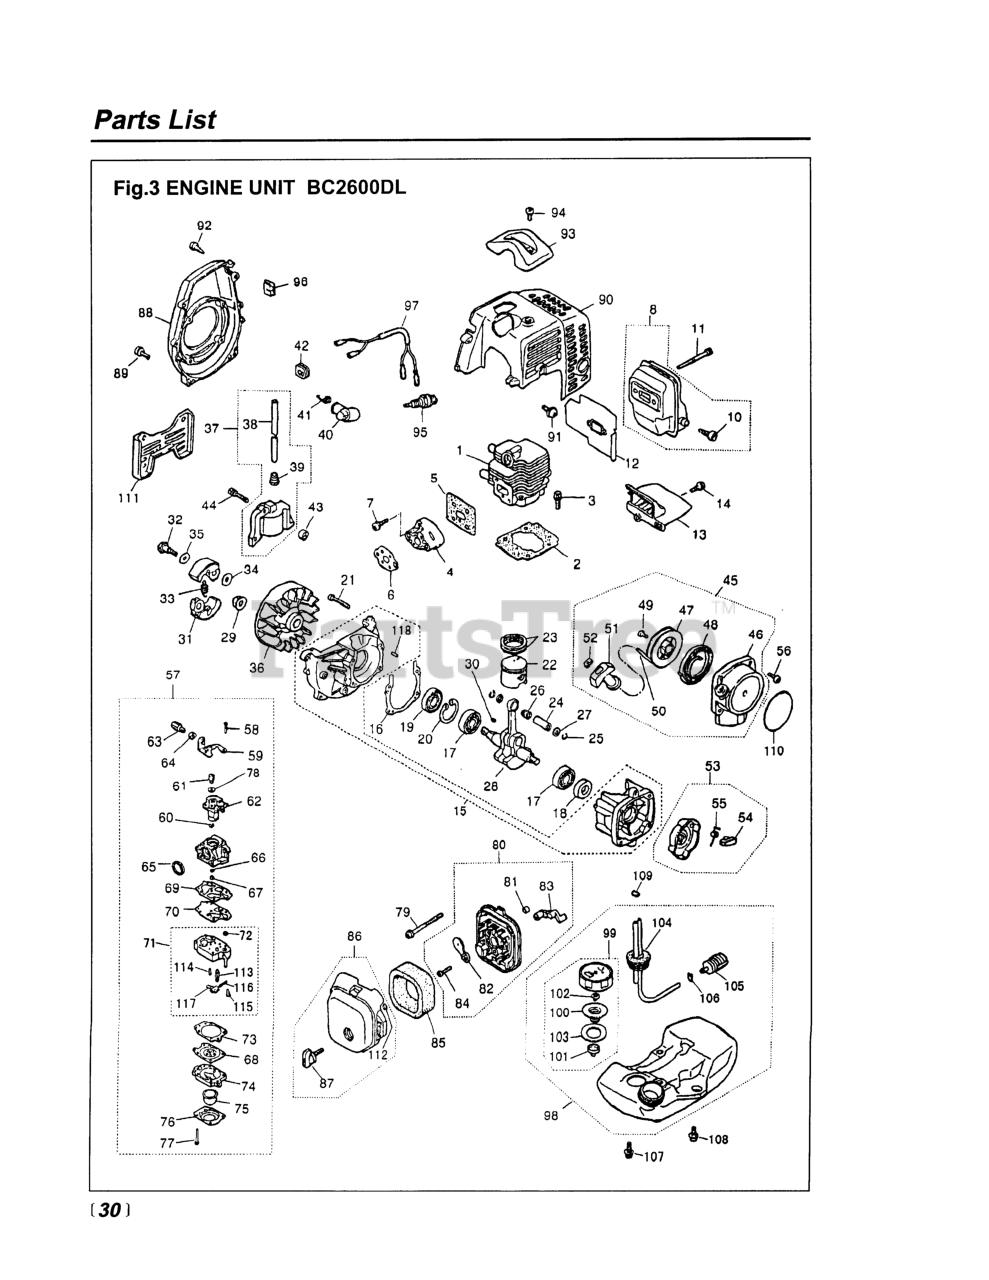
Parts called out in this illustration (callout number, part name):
1	CYLINDER
3	BOLT, M5 X 22
4	INSULATOR (USE -13163)
5	GASKET (RPLS -13120)
6	GASKET (REPLACES -13130)
7	SCREW, M5X20 (RPLS.1400-75510)
8	MUFFLER ASSY (RPLS 5501- )
10	ARRESTER (RPLS 5850-15140)
11	BOLT, M5 x 50
12	GASKET, MUFFLER (RPLS -15111)
14	SCREW, M4 X 16
15	CRANKCASE
16	GASKET (RPLS -21140)
17	BEARING
18	SEAL, OIL (RPLS 1100-21210)
19	SEAL, OIL (RPLS 1140-21220)
20	RING, SNAP, M28 x 1.2
21	BOLT, M5 X 30
22	PISTON
23	RING, PISTON
24	PIN, PISTON
25	RING, SNAP (RPLS 1101-41320)
27	WASHER
28	CRANKSHAFT (RPLS 1850-42000)
30	KEY
31	SHOE (RPLS 1100-51114)
32	BOLT
33	SPRING, CLUTCH (RPLS-51220)
34	WASHER, FLAT (USE 182303)
36	ROTOR
37	COIL ASSY (RPLS 5500-71200)
38	CORD
39	CAP
41	SPRING
42	GROMMET
43	SPACER (RPLS -71260)
44	BOLT
45	RECOIL ASSEMBLY
46	CASE
47	REEL
48	SPRING, SPIRAL
49	SCREW (RPLS -75150)
51	KNOB
52	PLATE, STOPPER
53	PULLEY ASSY (RPLS -75210)
54	RATCHET (RPLS 1850-75220)
55	SPRING, RETURN
56	SCREW, M4 X 16
57	CARBURETOR (WYJ-117)
58	SCREW
60	RING
61	SWIVEL
62	VALVE ASSY
63	SCREW, CABLE ADJUSTER
64	NUT, CABLE ADJUSTER
65	RING, PACKING
66	RING, O
67	JET
68	DIAPHRAGM (USE 4810-81260)
69	GASKET, PUMP
70	DIAPHRAGM
71	BODY, PUMP
73	GASKET, DIAPHRAGM
74	BODY, PURGE
75	PUMP, PRIMING
76	COVER, PUMP
77	SCREW
78	WASHER
79	SCREW, M5 X 55
80	BODY-A (RPLS -82101)
81	SLEEVE
82	PLATE, CHOKE (RPLS-82130)
83	LEVER, CHOKE
84	SCREW (REPLACES 50030272)
85	ELEMENT
87	KNOB (RPLS -82220)
88	COVER, FAN (RPLS-31110)
89	SCREW, M5X20 (RPLS.1400-75510)
90	COVER, ENGINE (RPLS -32111)
91	SCREW, M5 x 12
92	SCREW, HOUSING
93	GUARD, PLUG
94	SCREW,M5 X 14 (RPLS 1400-15510
97	CORD COMP (RPLS -73200)
101	HOLDER, CAP
102	VALVE (NLA WHEN OUT)
103	PACKING
104	PIPE COMPLETE
105	FILTER (RPLS 1850-85300)
106	CLIP (REPLACES 2841-31280)
107	SCREW
108	SCREW W/ WASHER
109	CLIP
110	LABEL, RECOIL (RPLS -91120)
111	STAND
112	RING
113	VALVE, INLET
114	SPRING, METERING LEVER
115	SCREW, METERING LEVER PIN
116	PIN, METERING LEVER
117	LEVER
118	PIN
